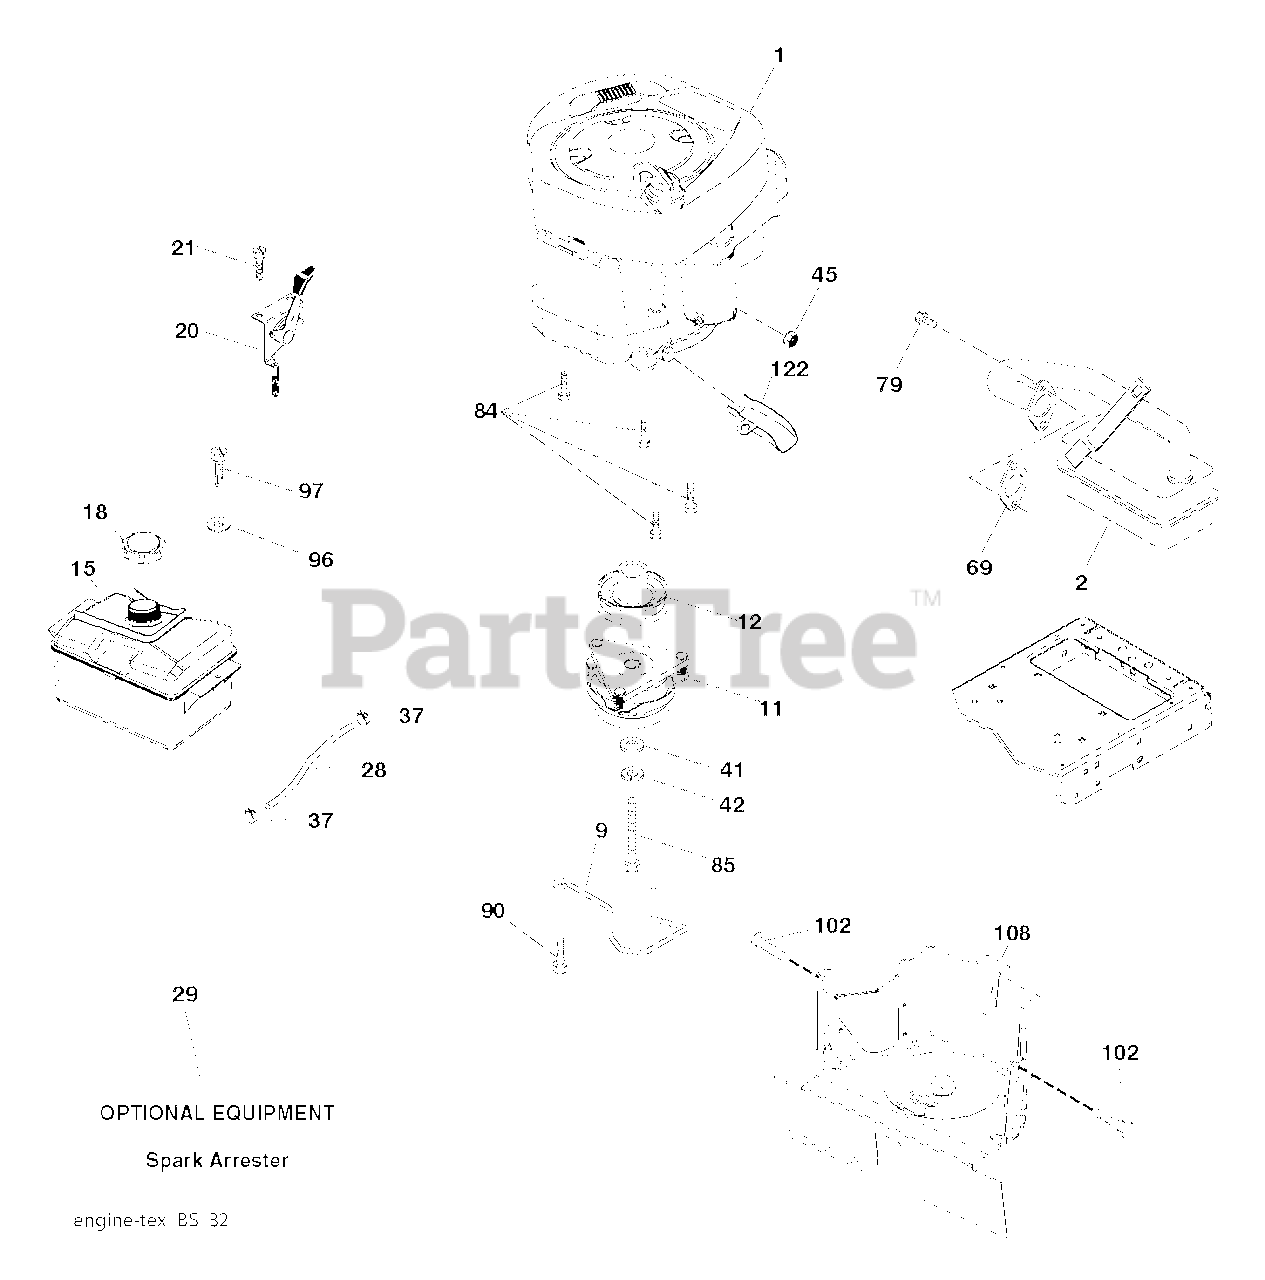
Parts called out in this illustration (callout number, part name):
2	MUFFLER.B&S.MODEL.21.11HP.OHV
9	KEEPER.BELT.ENGINE.3.25 (3 2)
11	RB.CLUTCH.OGURA.4.4.PD
12	PULLEY.ASM.ENG.OGURA.3
15	RP TANK FUEL FRT 1.5 GAL
18	CAP ASM.FUEL.2.25"FR.
20	CONTROL.TH/CK.C.
21	SCREW.#10 X 0.750.BOS
28	LINE.FUEL.20
29	KIT.SPARK ARRESTOR 794945 B&S
37	HOSE CLAMP
42	LOCKWASHER
45	NUT
69	REPL BY 532 27 22-93
79	SCREW.SOCKET HD.5/16-1
84	SCREW.3/8-16
85	BOLT HEX 7/16-20X4-1/4"
90	SCREW 3/8-16X1
97	SCREW HEXWSHR 1/4-20X3/4
102	SCREW
108	COVER PULLEY
122	EXTENSION DRAIN OIL
